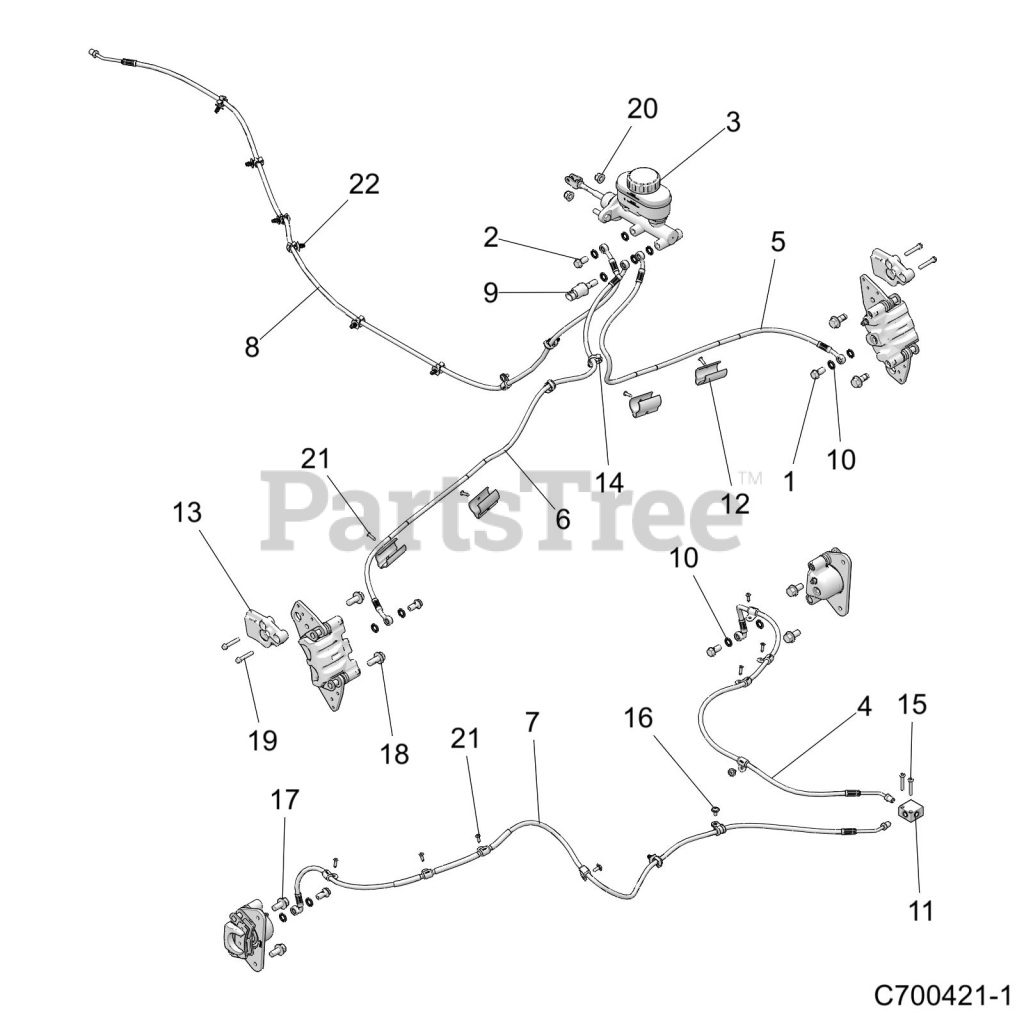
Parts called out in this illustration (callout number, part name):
1	BOLT-BANJO,10MMX1.00
2	BOLT-BANJO, 10MM X 1.25-6G
3	ASM-M/C-T-FLANGE,3/4 BORE
4	LINE-BRK,RL,41.1,45F,90SB,290J
5	LINE-BRK,FL,35.2,45B,20B,120°J
6	LINE-BRK,FR,41.7,70B,20B,85°J
7	LINE-BRK,RR,60,45F,90SB,120°JF
8	LINE-BRK,M/T,72.7,20B,20F,263
9	SWITCH-BRK,M10X1.25,DBL,SEALED
10	SEAL-STAT-O-3/8,70EP
11	FITTING-TEE,BRAKE
12	RETAINER-BRAKE LINE,1"
13	SCRAPER-BRAKE,FRONT
14	CLIP-ROUTING
15	SCR-10-24X1.25TFM PN TRX TRI-Y
16	SCREW(10)
17	BOLT-M10X1.25X20,HXFLG-OLV D
18	BOLT-M10X1.25X25,HXFLG,W/PATCH
19	SCR-HXFL,M6X1.0X35,W/PATCHLOK
20	NUT-M8X1.25,FLG,NYLOC-OLIVE D
21	POP RIVET(50)
22	CLIP-NYLON,C,FIR-TREE
